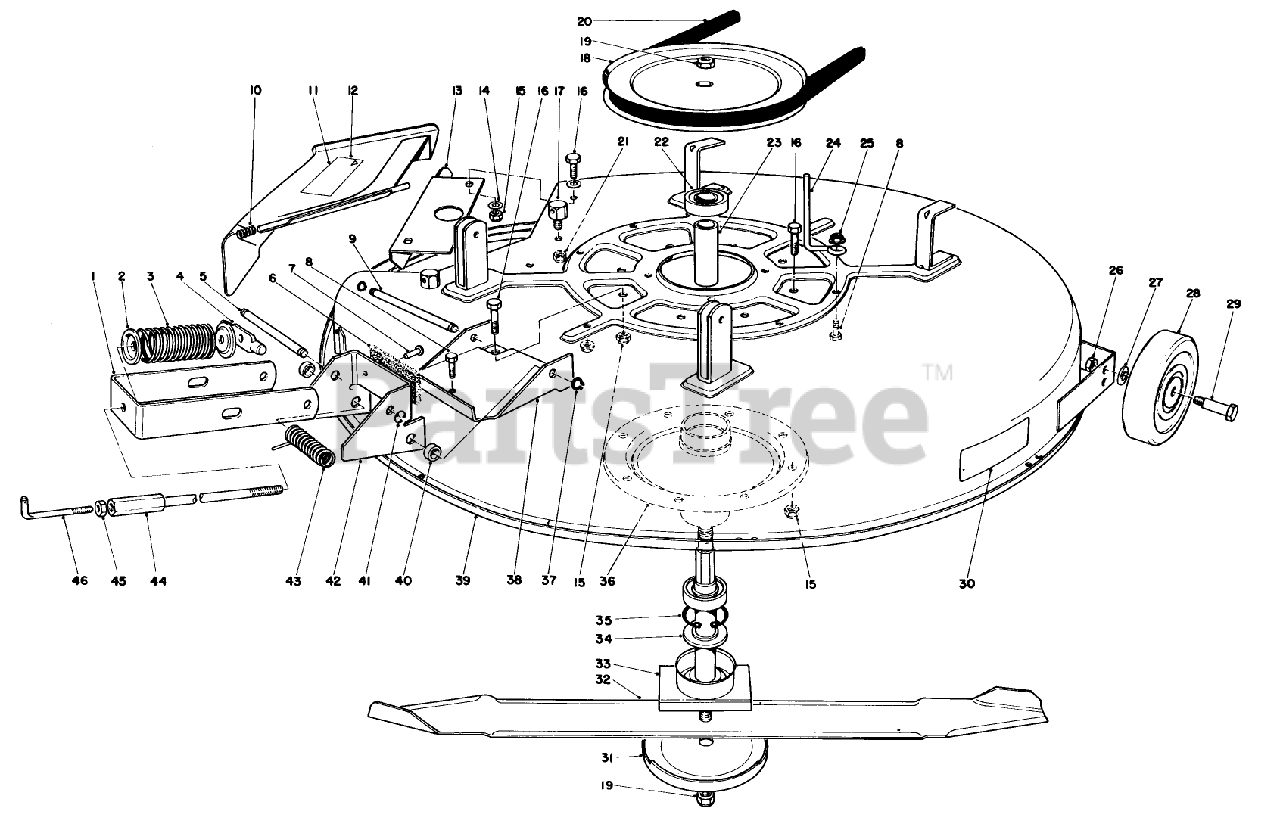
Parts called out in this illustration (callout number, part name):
1	Bracket-Engagement
2	RETAINER-SPR. TOP
3	SPRING-COMPRESSION
4	SHAFT-DECK ADJ.
5	Pin-Clevis
6	BRAKE PAD
7	RIVET .187 X 7/16 BRASS
8	SCREW-HH
9	CLEVIS PIN
10	SPRING
11	Deflector Assembly (Incl. Ref. #12)
12	Decal
13	Baffle Deck
14	WASHER-PLAIN
15	NUT-LOCK, NI
16	SCREW-HH
17	POST-PIVOT
18	PULLEY
20	V-BELT, DECK
21	NUT-LOCK, SIDE
22	BEARING-BALL
23	Spacer-Bearing
24	BELT GUIDE
25	NUT-LOCK, HHF
26	Nut
27	WASHER-FLAT
28	DECK WHEEL
30	DECK DECAL
31	Cup
32	Blade
33	SPINDLE SHAFT WA
34	SPACER-SPINDLE
35	RING-RETAINING
36	Spindle Body
37	RING-RETAINING
38	DECK ENGAGE CHANNEL R
39	Cutter Deck
40	DECK BRAKE SPACER
41	E-RING
42	Support Deck Brake Assembly (Incl. Ref. #6 & 7)
43	SPRING
44	ADJ HUB WA
45	NUT-JAM
46	ADJ. ROD
